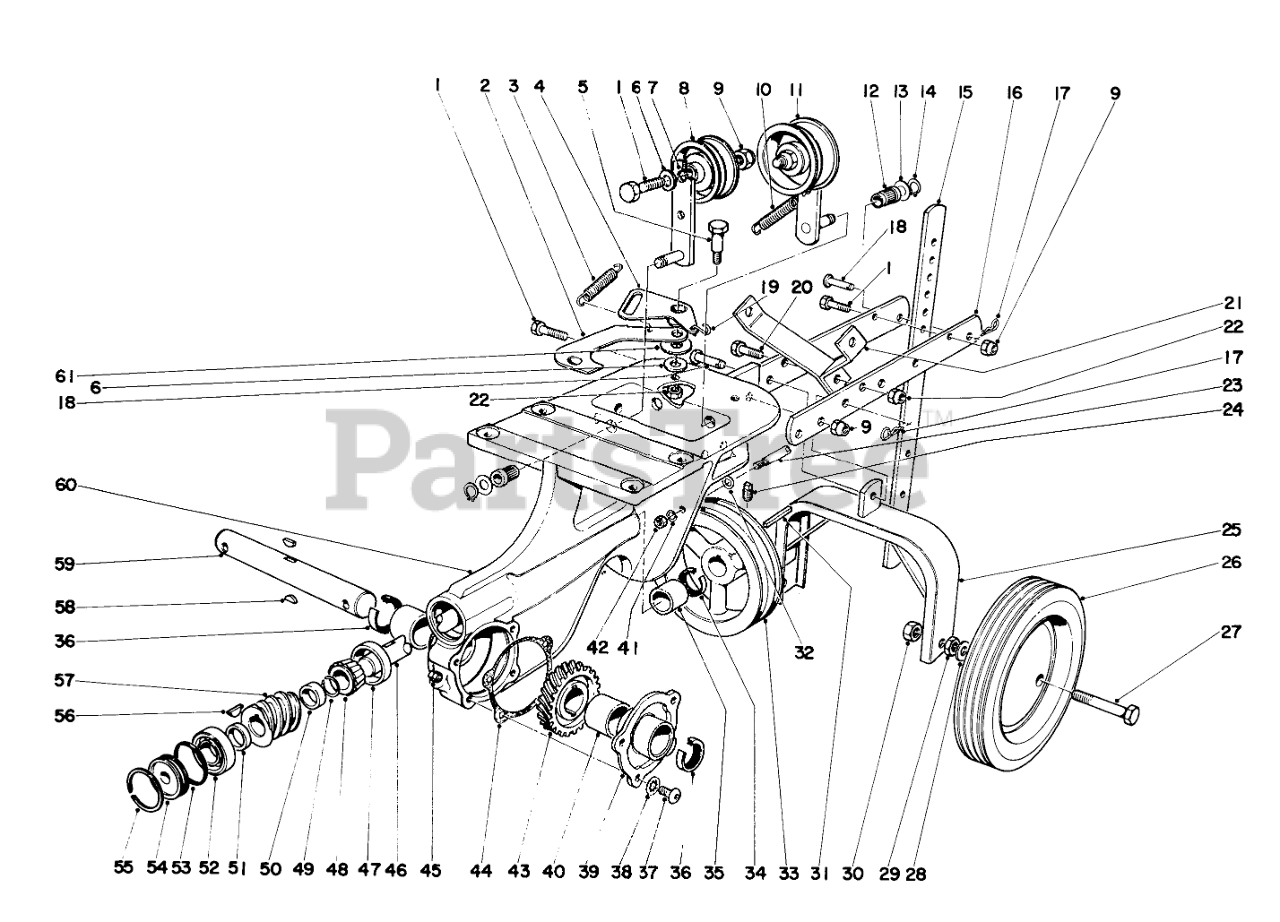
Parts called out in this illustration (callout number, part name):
1	SCREW-HH
2	Rev. Link
3	Spring
4	Bellcrank
5	SCREW-SHOULDER, HH
6	WASHER-FLAT
7	Idler
8	PULLEY IDLER
9	NUT-LOCK, CONE
10	Spring
11	PULLEY-IDLER
12	IDLER BRG
13	WASHER-PLAIN
14	RING-RETAINING, EXT
15	DEPTH GAGE
16	Drawbar
17	PIN-COTTER, HAIR
18	Pin
19	S Hook
20	SCREW-HH
21	Handle Support
22	NUT-LOCK, CONE
23	Belt Guide
24	SCREW-SET, HSH
25	Wheel Bracket
26	Wheel
27	Axle
28	WASHER-FLAT
29	NUT-JAM
30	1/2-13 CONELOCK NUT
31	KEY-SQUARE
32	WASHER-FLAT
33	Pulley
34	SEAL-OIL
35	BUSHING
36	SEAL-OIL
37	SCREW-HSBH
38	WASHER-LOCK
39	Cover
40	Bearing
41	WASHER-LOCK/EXT
42	NUT-JAM
43	WORM WHEEL
44	GASKET
45	PLUG-PIPE, SQH
46	WORM SHAFT
47	1.750 ROLLER BRG CUP
48	3/4 ROLLER BRG CONE
49	RETAINER RING
50	WORM SHF REAR SPACER
51	SPACER
52	.750 BALL BEARING
53	O-RING
55	INTRNL RETAINING RING
56	KEY-WOODRUFF
57	WORM GEAR
58	KEY-WOODRUFF
59	WORM WHEEL SHAFT
60	Chassis
61	WASHER-FLAT
